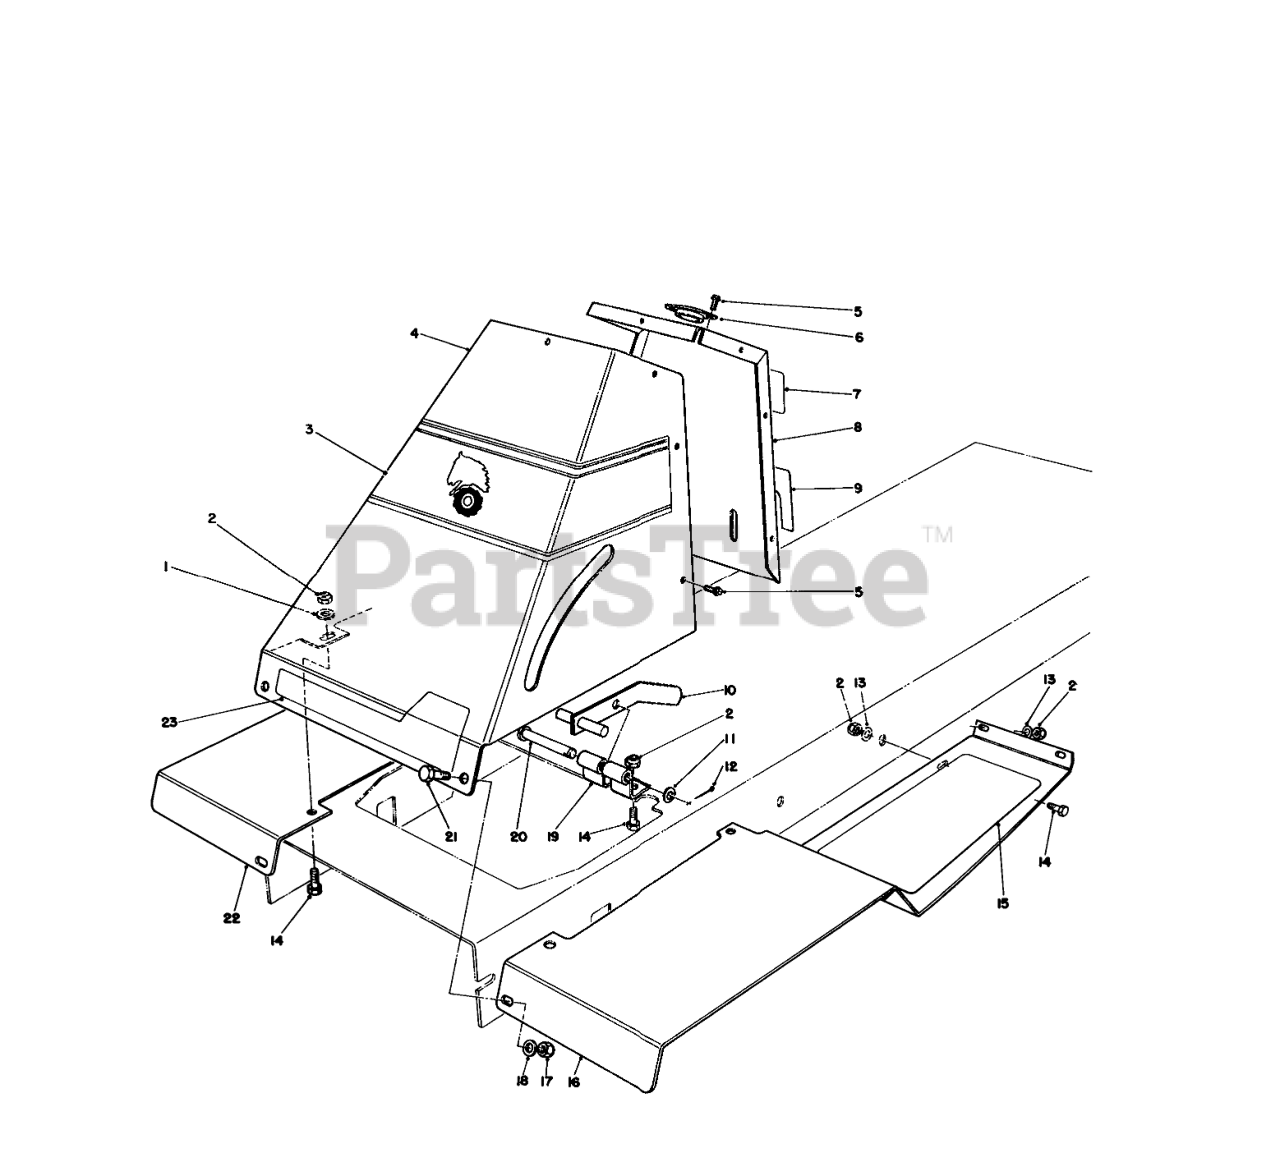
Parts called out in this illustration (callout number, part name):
1	WASHER-FLAT
2	NUT-LOCK, NI
3	DECAL - STEERING SUPT
4	Tower-Front
5	SCREW-HWHTF
6	GUIDE-STRG SHAFT
7	DECAL-DANGER
8	Tower-Rear
9	PARK BRAKE DECAL
10	PARKING BRAKE WA B
11	WASHER-FLAT
12	PIN-COTTER
13	WASHER-PLAIN
14	SCREW-HH
15	FOOT TREAD L.H.
16	Footrest-LH
17	NUT-LOCK, NI
18	WASHER-FLAT
19	Bracket-Parking Brake
20	PIN-CLEVIS
21	SCREW-HH
22	Footrest-RH.
23	DECAL/RECYCLER 32" FRT
